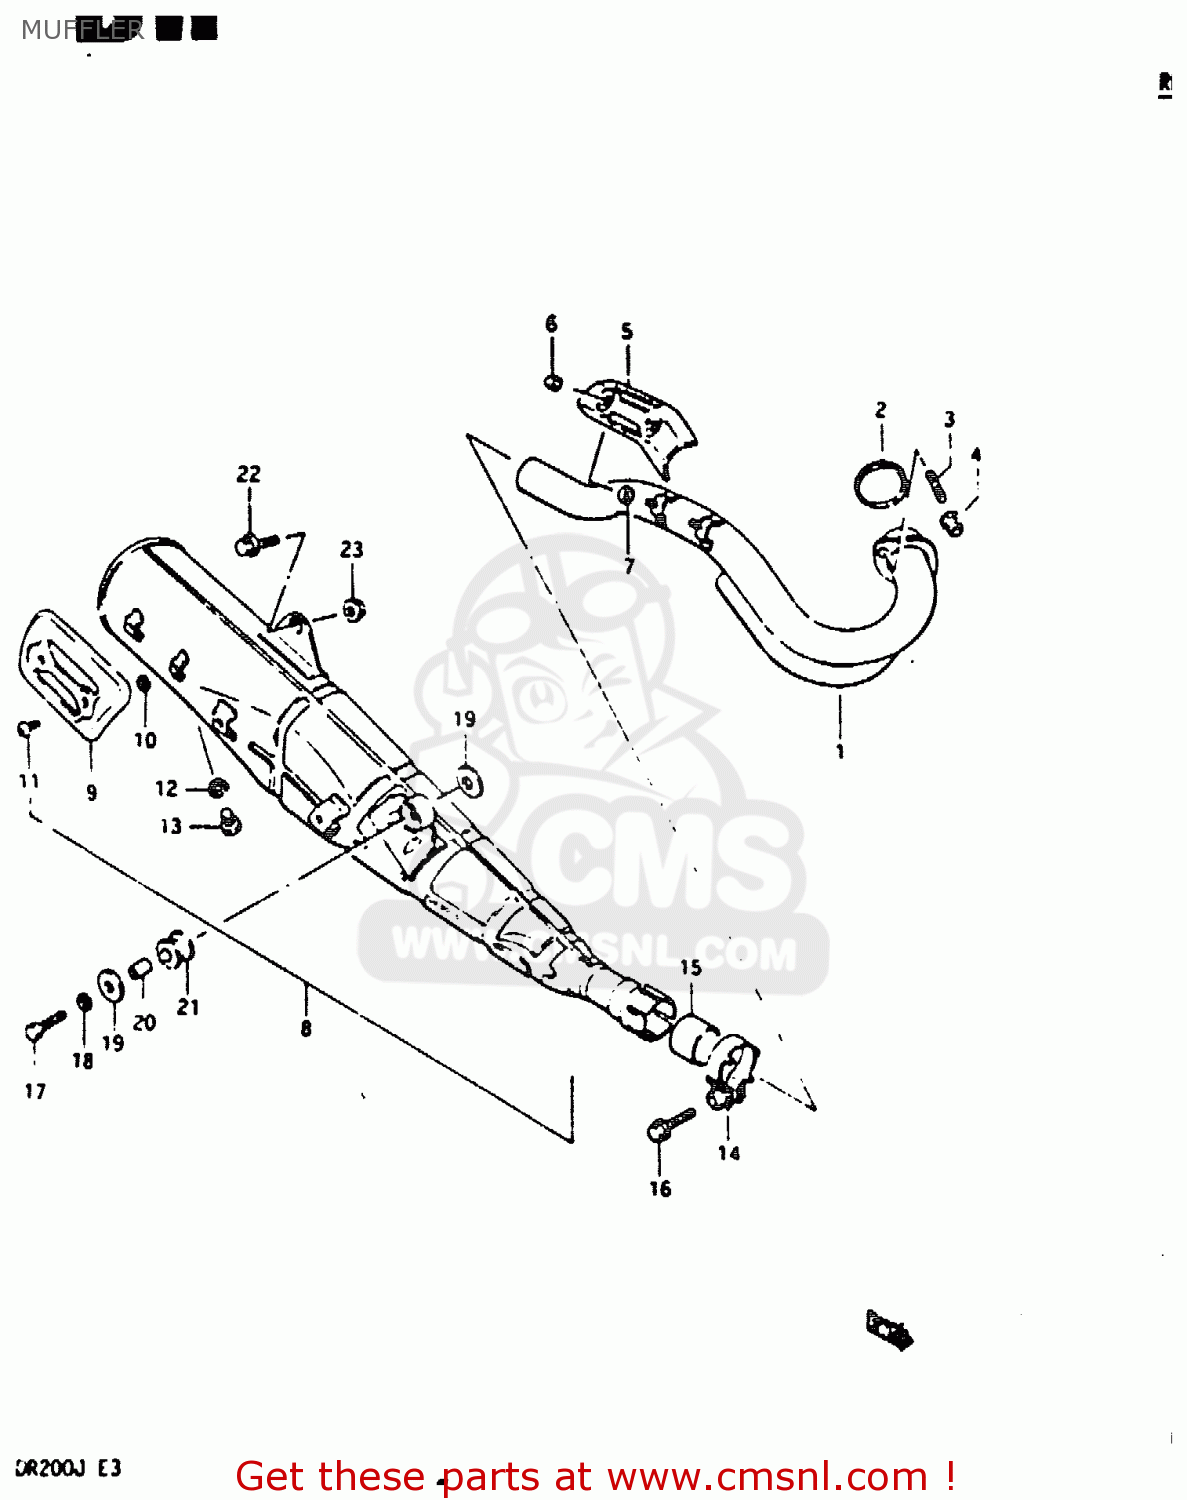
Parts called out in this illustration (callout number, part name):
1	PIPE COMP,EXHAUST
2	GASKET,EXHAUST PIPE (NAS)
3	BOLT,STUD
4	NUT
5	COVER,EXHAUST PIPE
6	NUT (6MM)
7	GASKET (NAS)
8	MUFFLER ASSEMBLY
9	COVER,MUFFLER
10	GASKET (NAS)
11	SCREW
12	GASKET(12.1X16.2X3.7) (NAS)
13	PLUG(12X9)
14	CLAMP,MUFFLER CONNECTOR
15	GASKET,SECOND MUFFLER (NA) (NAS)
16	BOLT
17	BOLT
18	WASHER,LOCK,8.
19	WASHER (8.5X20X1.6)
20	SPACER (8.6X12X17.5)
21	CUSHION
22	BOLT(8X25)
23	NUT
